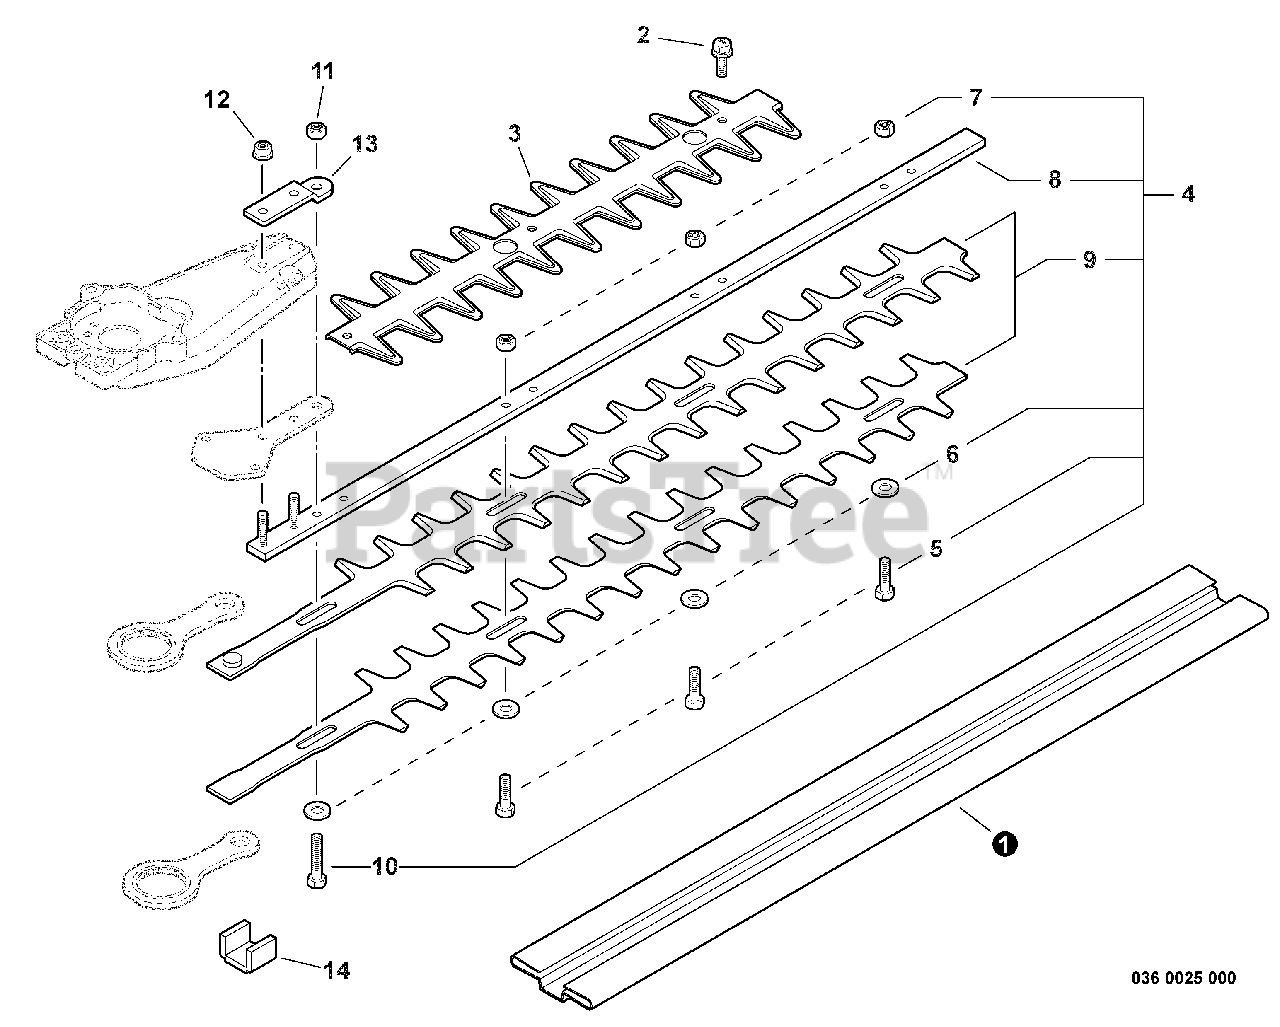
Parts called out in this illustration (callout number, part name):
1	COVER, BLADE - 24" (60cm)
2	BOLT - 5X8
3	SHIELD, BLADE
4	BLADE KIT - 24" (60cm)
5	BOLT - 6X20
6	WASHER - 6
7	LOCKNUT - 6
8	SUPPORT, BLADE - 24" (60cm)
9	BLADE - 24" (60cm)
10	BOLT - 6
11	LOCKNUT - 6
12	NUT - 5 -- FLANGE
13	PLATE, ANGLE
14	SEAL, FELT
